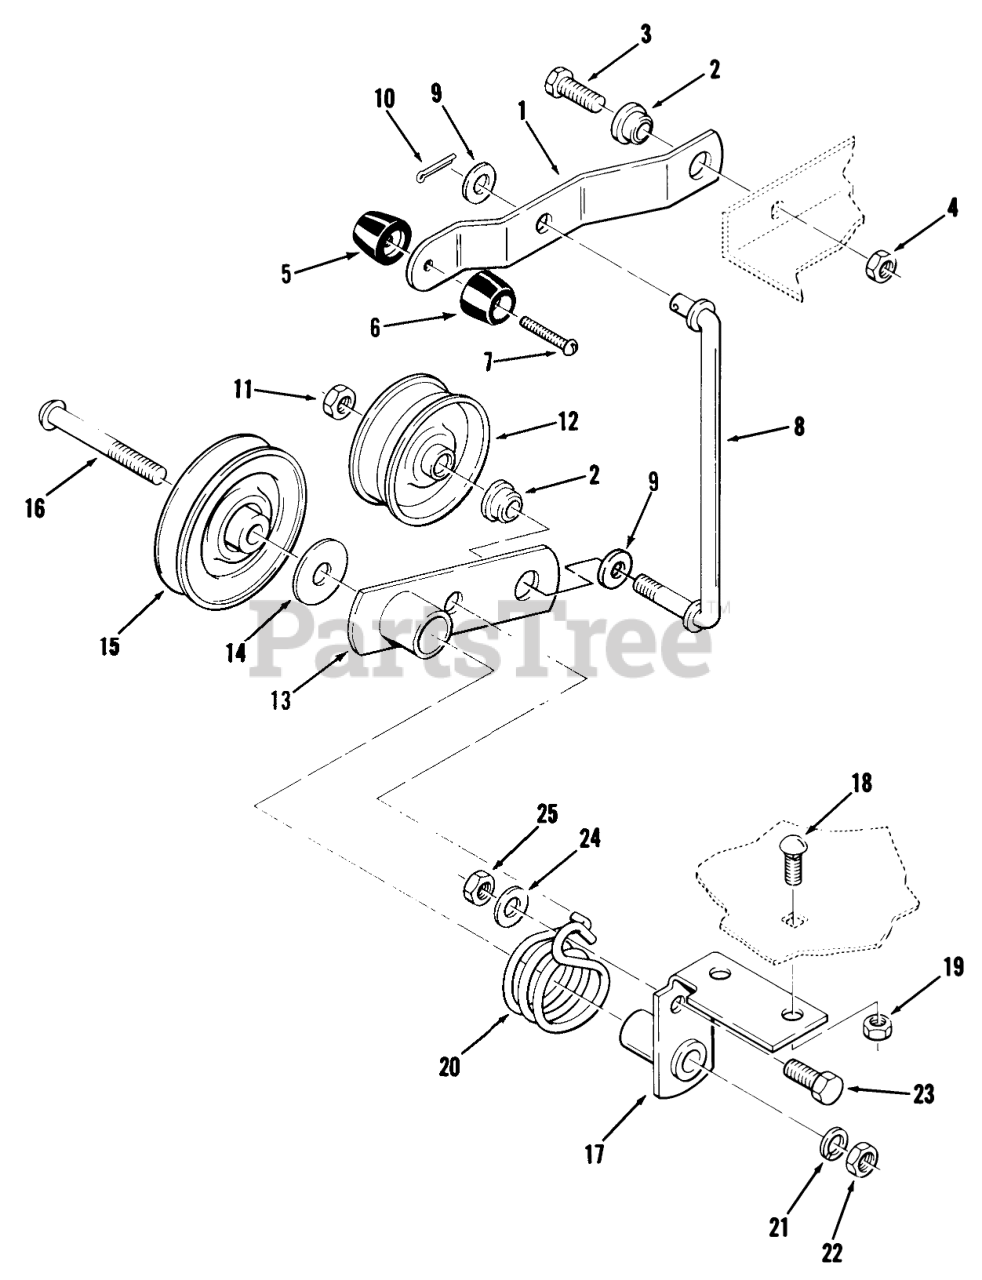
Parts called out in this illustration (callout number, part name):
1	LEVER
2	SPACER-BRAKE LINK
3	BOLT
4	Nut
5	KNOB
6	KNOB
7	BOLT-4
9	Washer
10	Pop Rivet
11	Nut
12	IDLER PULLEY
13	ASSY-IDLER ARM
14	WASHER
15	PULLEY-IDLER
16	SCREW 3/8-16X23/4
17	Idler Arm Support
18	Bolt
19	Nut
20	SPRING-TORSION
21	LOCKWASHER
22	Nut
23	Bolt
24	Washer
25	Nut
